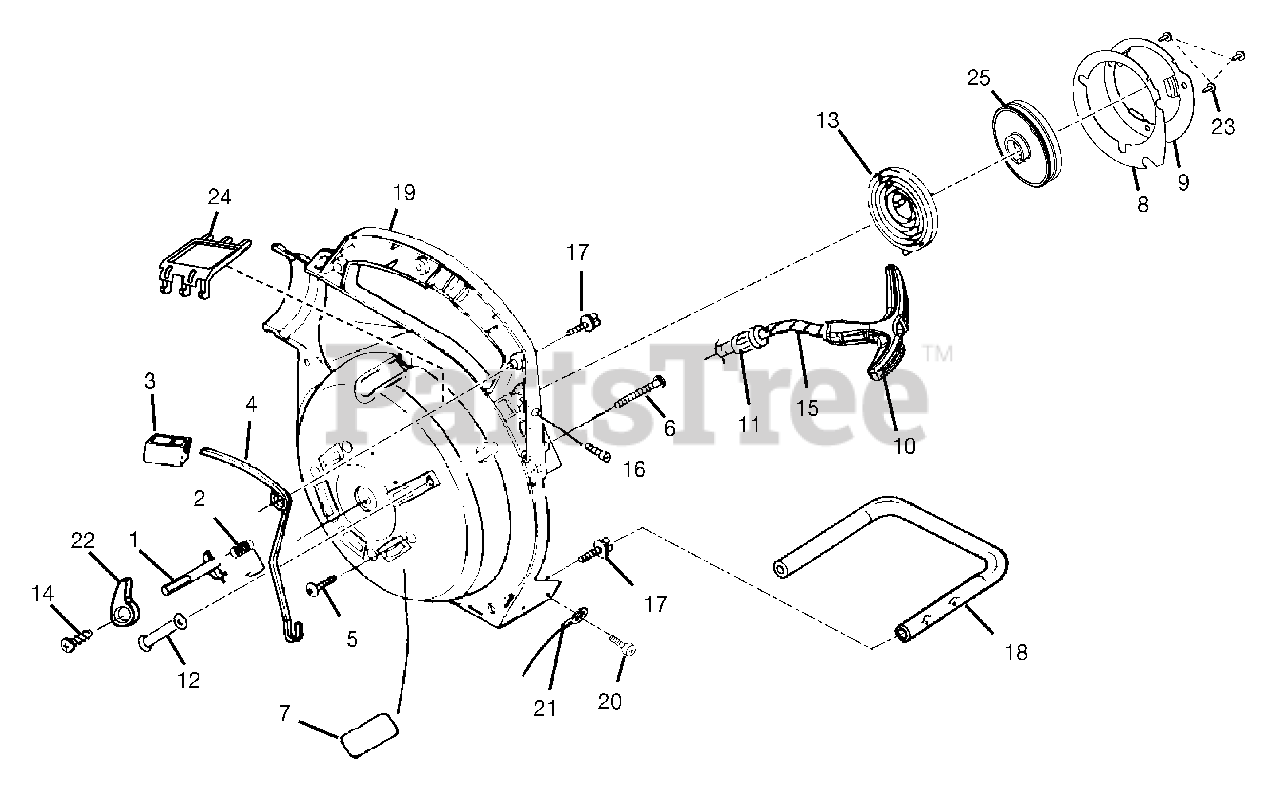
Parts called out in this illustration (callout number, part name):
1	THROTTLE LATCH
2	THROTTLE LATCH SPRING
3	THROTTLE TRIGGER
4	THROTTLE LEVER
5	SCREW (10-24 x 3/4 in.TRUSS HD.)
6	SCREW (10 x 1-5/8 in. HEX HD.)
7	HEAT SHEILD
8	BAFFLE GASKET
10	STARTER GRIP (YELLOW)
11	Bu SHING STARTER
12	STARTER ROPE GUIDE
13	SPRING AND CONTAINER
14	SCREW (10-24 x 1/2 in. TORx TRu SS HD.)
15	ROPE STARTER
16	SCREW (8-32 x 5/8 in. FIL. HD.)
17	SCREW (10-14 x 3/4 in. TORx TRu SS HD.)
18	LOw ER HANDLE
19	INNER v OLu TE HOu SING
20	SCREW (8-18 x 1/2 in. PAN HD.)
21	LEAD-GROUND
22	THROTTLE CONTROL KNOB
23	SCREW
24	SCREEN COVER
25	PULLEY ASSEMBLY
